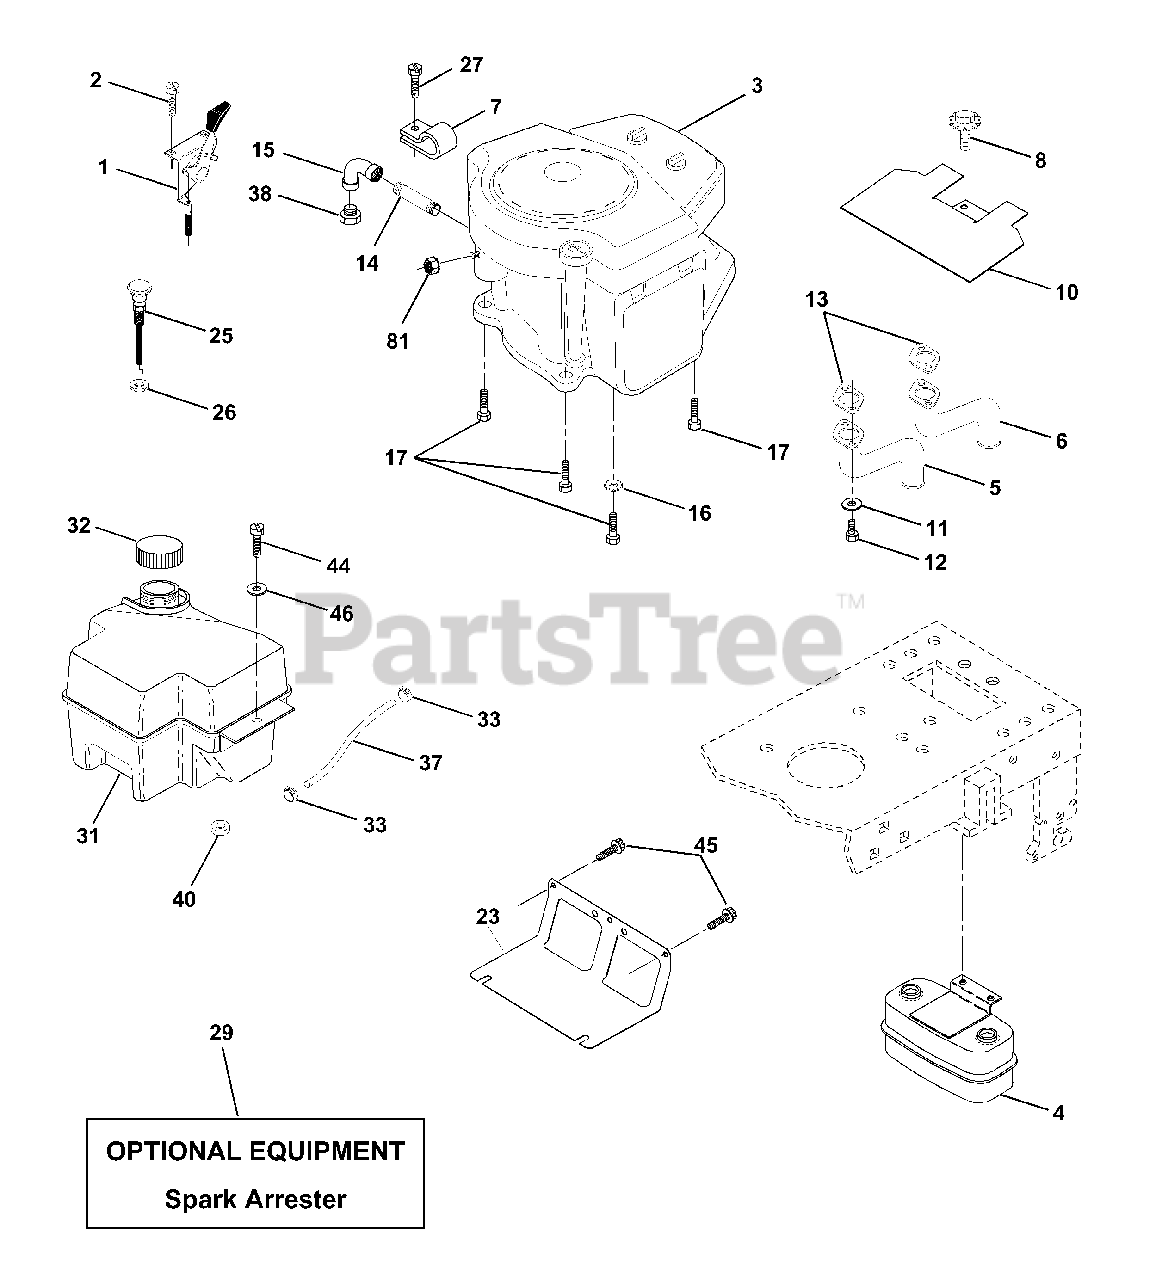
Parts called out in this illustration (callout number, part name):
1	Control Throt
2	Screw Hex Thd Cut 1/4-20x5/8 T
4	Muffler Exhaust
5	Exhaust Asm. Left
6	Exhaust Asm. Right
7	Clamp Tube Double Engine
8	Bolt 5/16-18unc x 3/4 w/sems
10	Heat Shield Lt
11	Washer Lock Hvy. Helical 1/4
12	Bolt Fin Hex 1/4-20 x 3/4
13	Gasket Muffler
14	Nipple Pipe 4-1/2"
15	Elbow Std 90 Degree 3/8-18 Npt
16	Washer Lock Ext Tooth 3/8
17	Screw Thdrol 3/8-16x1-1/2 Tytt
23	Shield BRN/DBR Guard
25	Control Choke
26	Nut Keps 3/8-24 UNF
27	Screw TT Flange
29	Arrestor Spark
31	Tank Fuel
32	Cap Fuel
33	Clamp Hose Blk
37	Line Fuel
38	Plug Oil Drain
40	Bushing Snap Nyl Blk Fuel Line
44	Screw Hexwsh Thdrol 1/4-20 x 3/4
45	Screw Hex wsh Thdrol 3/8-16 x 3/4
46	Washer 9/32 x 7/8 x 16 Ga
81	Nut Keps Hex 1/4-20 unc
